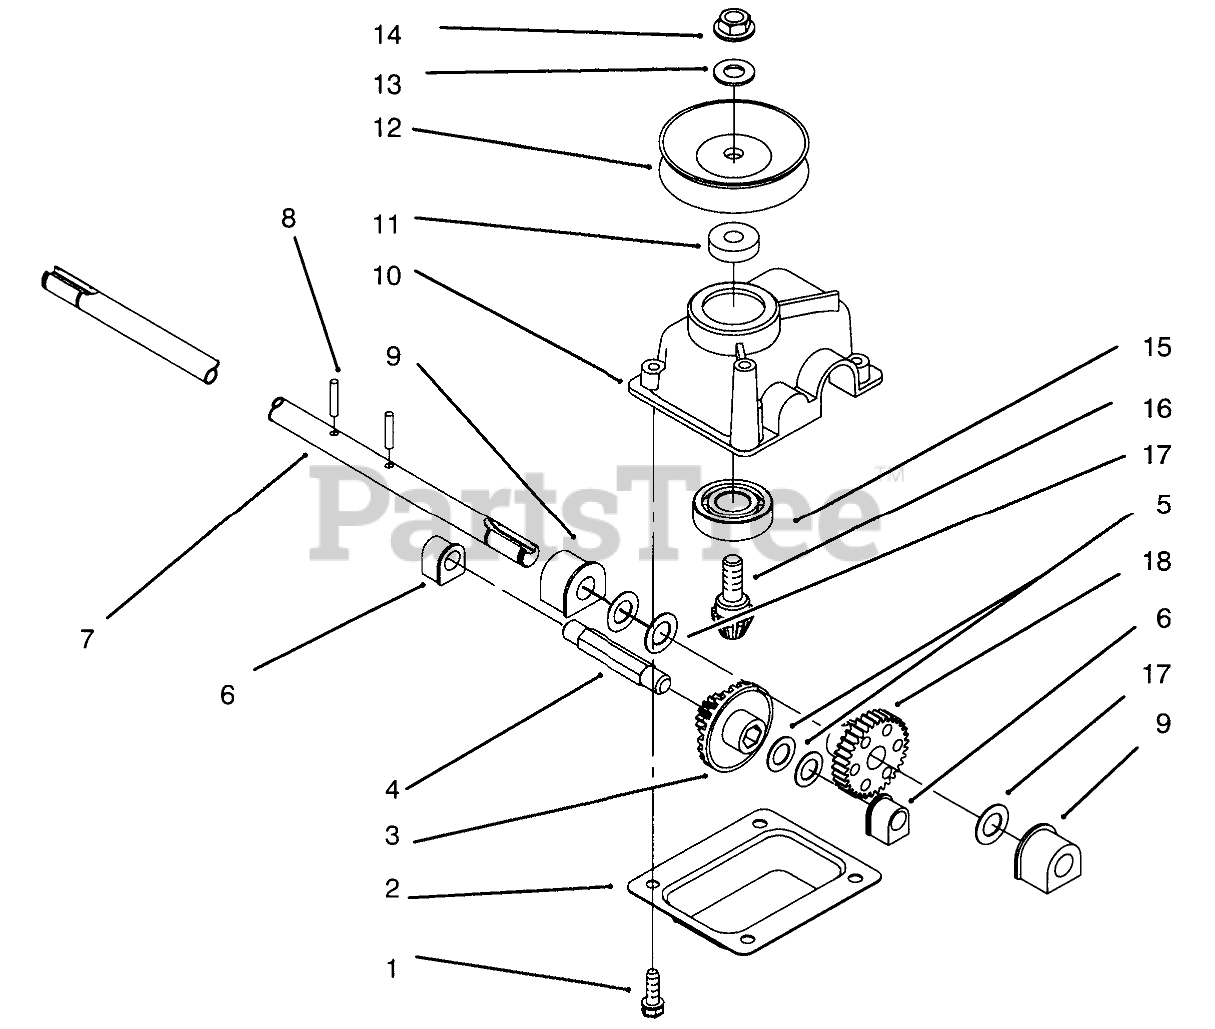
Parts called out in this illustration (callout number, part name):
1	SCREW-HWHTF
2	Cover-Gear Case
3	Gear-Bevel
4	SHAFT-INTERMEDIATE
5	WASHER-THRUST
6	BUSHING
7	OUTPUT SHAFT
8	5/32 X 7/8 ROLL PIN
9	BUSHING
10	GEARCASE
11	SPACER
12	PULLEY-DRIVEN HALF
13	WASHER-FLAT
14	NUT-HEX
15	BEARING-BALL
16	Gear-Pinion
17	WASHER-PLAIN
18	GEAR
